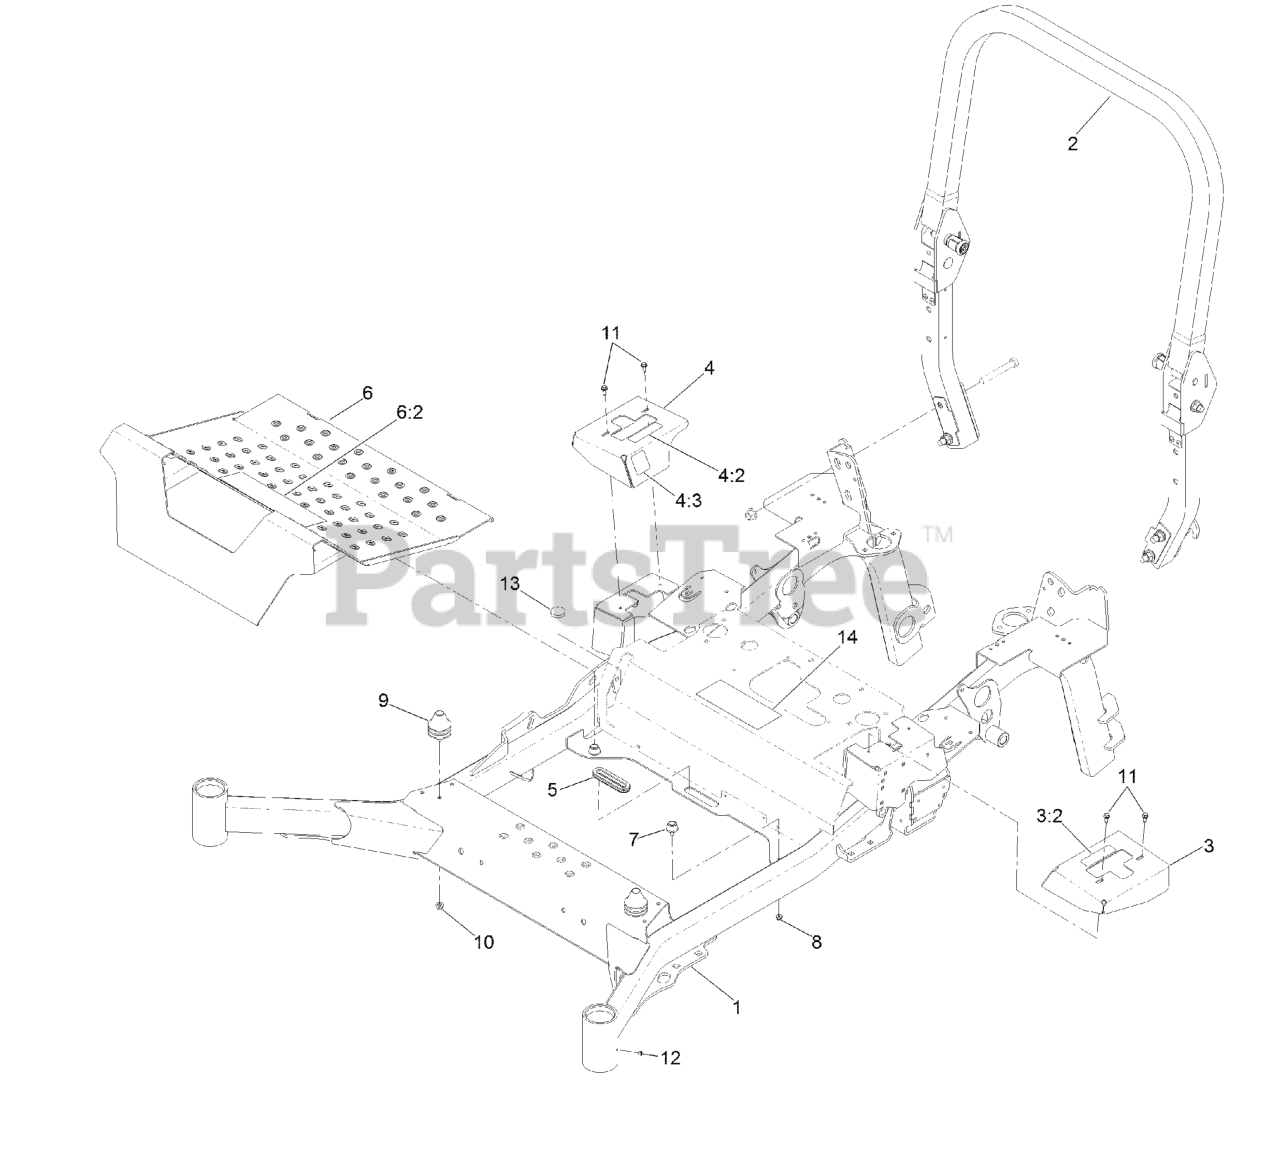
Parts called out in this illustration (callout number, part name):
2	ROPS ASM
3	COVER-MOTION CONTROL, LH
3:2	DECAL-CONTROL, MOTION
4	COVER-MOTION CONTROL, RH
4:2	DECAL-CONTROL, MOTION
4:3	DECAL-PARK BRAKE, CE
5	GROMMET-RUBBER
6	PAN-FLOOR
6:2	DECAL-DANGER
7	BUMPER-RUBBER
9	ISOLATOR
10	NUT-HF, NI
11	SCREW-HWH
13	BUMPER-PUSH-IN, RUBBER
14	DECAL-SERVICE AID
